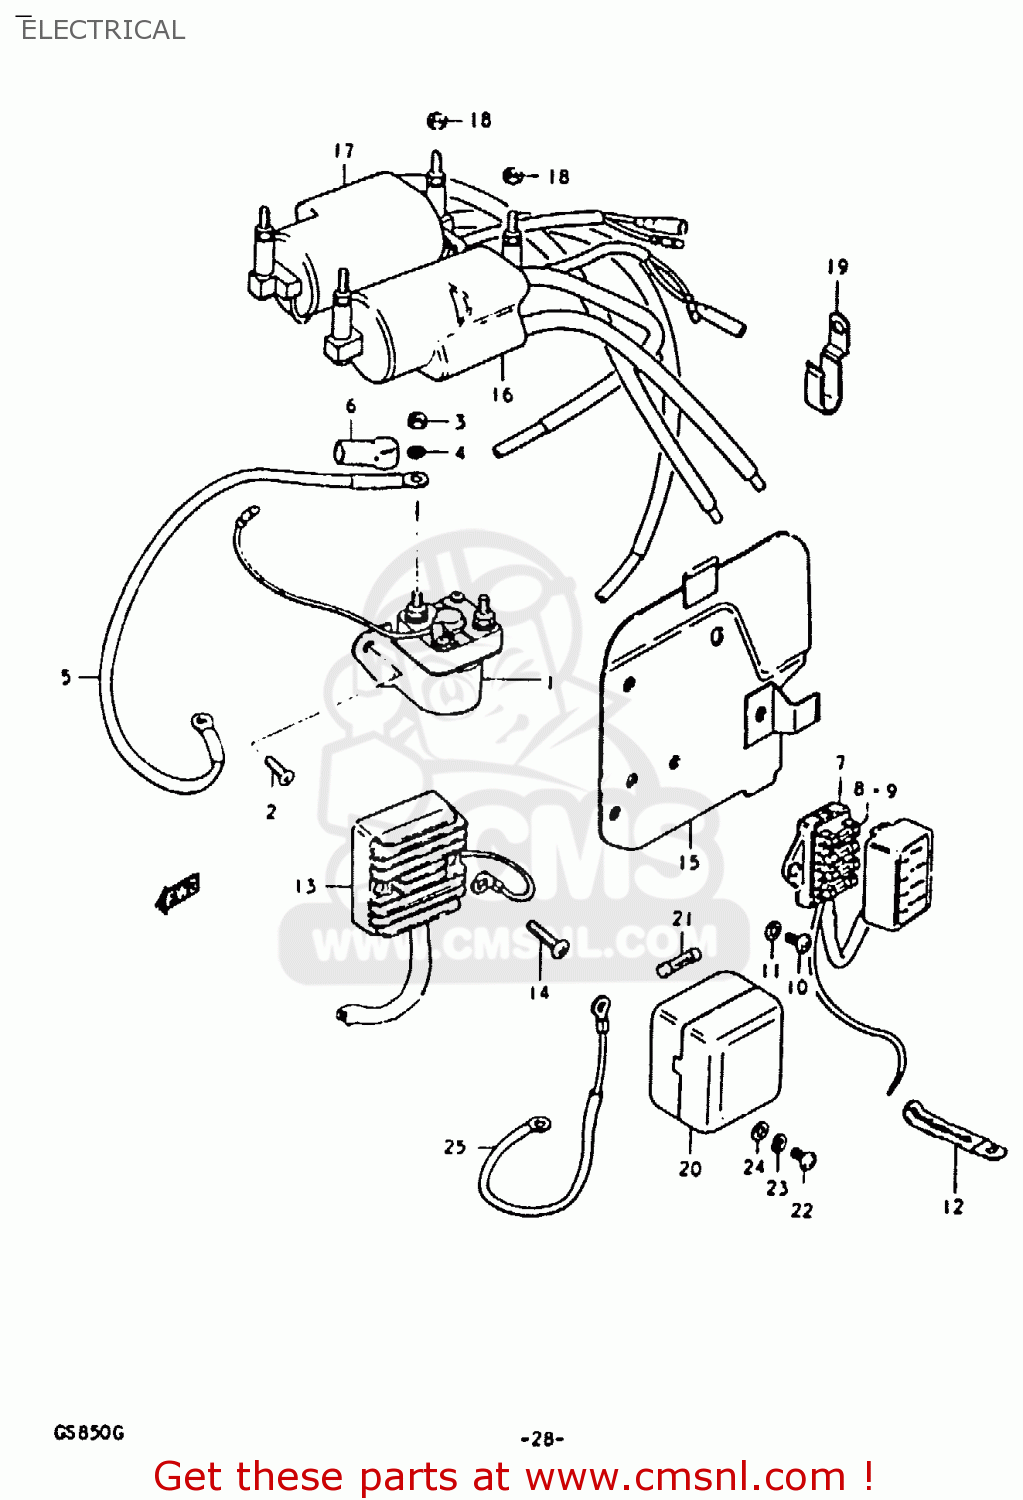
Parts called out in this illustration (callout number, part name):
1	RELAY ASSY,STARTING MOTOR
2	SCREW
3	NUT 6MM
4	LOCK WASHER
5	WIRE,STARTER MOTOR LEAD
6	CAP,STARTER RELAY
7	BOX ASSEMBLY,FUSE
8	FUSE(10A)
9	FUSE(15A)
10	SCREW 6X12
11	WASHER
12	CLAMP L:35
13	RECTIFIER ASSEMBLY
14	SCREW
15	HOLDER COMP,ELECTRONIC PARTS
16	COIL ASSEMBLY,IGNITION
17	COIL ASSEMBLY,IGNITION
18	NUT
19	CLAMP
20	TERMINAL ASSEMBLY,POWER SO
21	FUSE(10A)
22	SCREW
23	LOCK WASHER
24	WASHER
25	WIRE,POWER SOURCE LEAD
